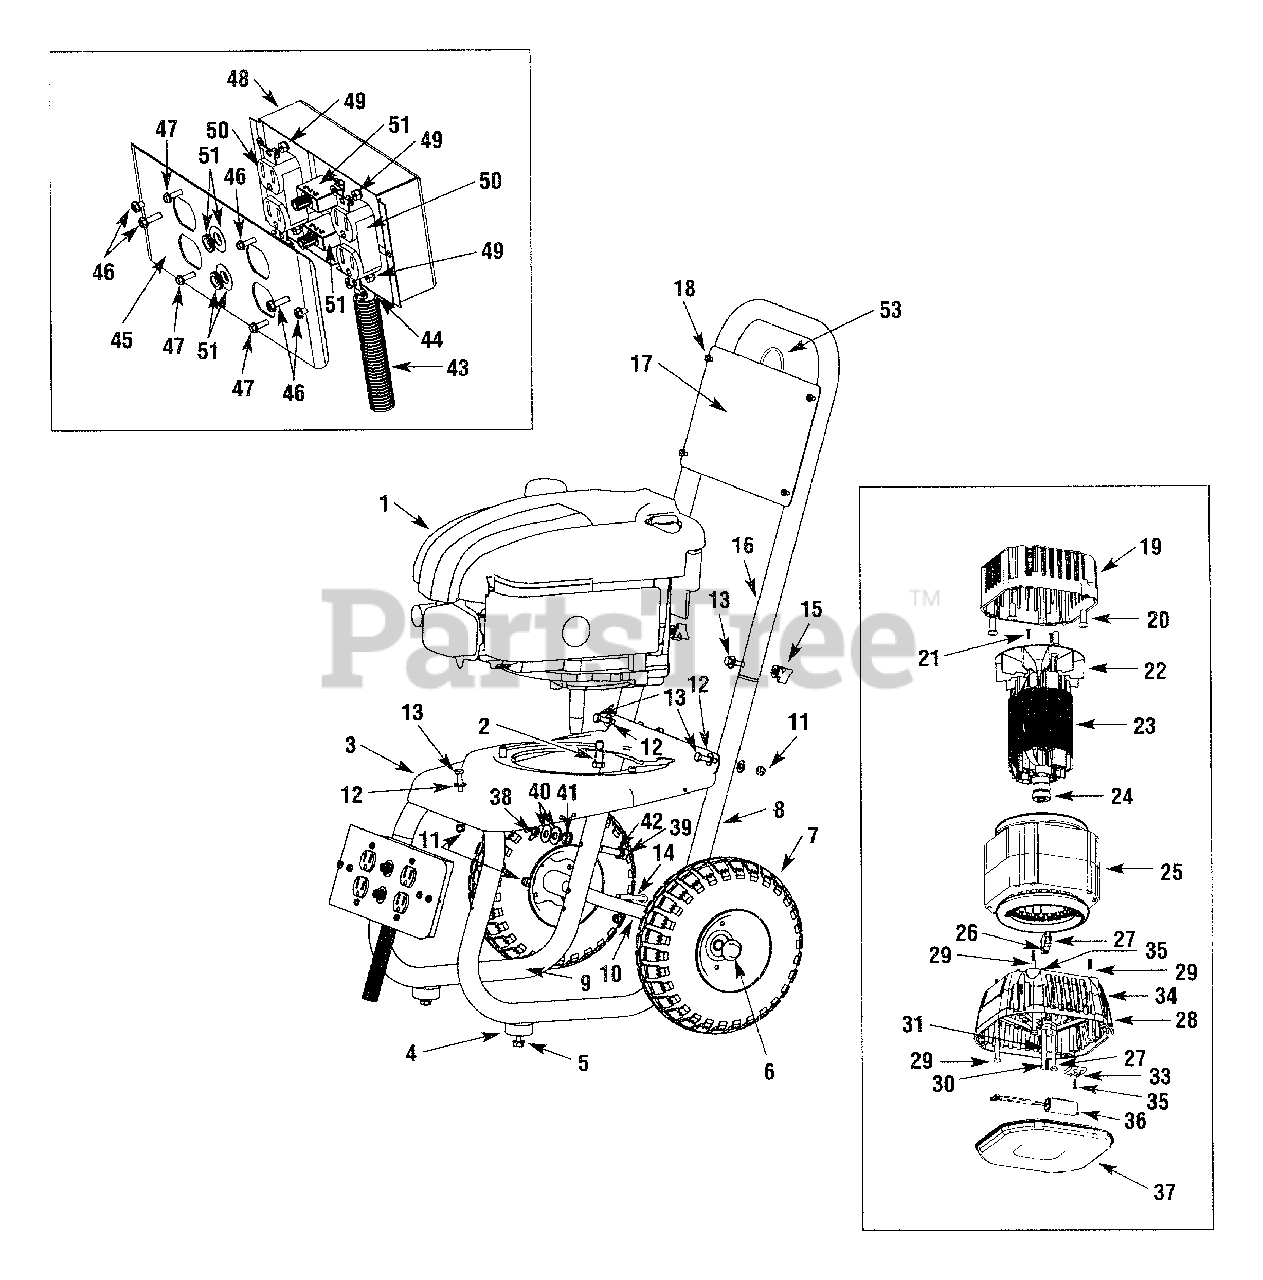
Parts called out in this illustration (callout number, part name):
1	Gasoline engine
2	3/8"-16 x 1" self tapping screw
3	Baseplate
4	Foot, vibration isolator
5	Screw, 1/4"-20 x 3/4" self tapping
6	Palnut
7	Wheel
8	Leg, left frame support
9	Leg, right frame support
10	Axle, vertical cart
11	Nut, 1/4"-20 Nyloc hex
12	Washer, 1/4" flat
13	Bolt, 1/4"-20 x 1-1/2" hex
14	Bolt, 1/4"-20 x 2-1/2" hex
15	Nut, 1/4"-20 thumb
16	Handle, vertical cart
17	Placard, vertical handle
18	Rivet, 3/16"
19	Adapter, engine
20	Screw, 3/8"-16 x 3/4" button socket
21	Screw, 8-18 x 5/8"
22	Fan, rotor
23	Assembly, rotor
24	Bearing, rotor
25	Assembly, stator
26	Kit, brush
27	Holder, brush
28	Endbell, bearing
29	Bolt, 1/4"-20 hex
30	Bolt, 5/16"-24 hex
31	Washer, 5/16" flat
33	Rectifier, 200V, 8A
34	Screw, #8 Hi-Lo
35	Screw, #10 self tapping type "F"
36	Assembly, 200uF capacitor
37	Cover, end
38	Nut, wing 5/16-18
39	Screw, 5/16-18 x 2-1/2" HHC
40	Washer, 5/16 flat
41	Nut, 5/16-18 serrated flange
42	Washer, 5/16 external tooth
43	Tubing, loom
44	Connector, snap in
45	Panel, electrical power
46	Screw, #10 self tapping
47	Bolt, #8 hex head
48	Cover, power panel rear
49	Nut, #8 Nyloc hex
50	Receptacle, 120V-15A duplex
51	Breaker, circuit
53	Holder, extension cord
